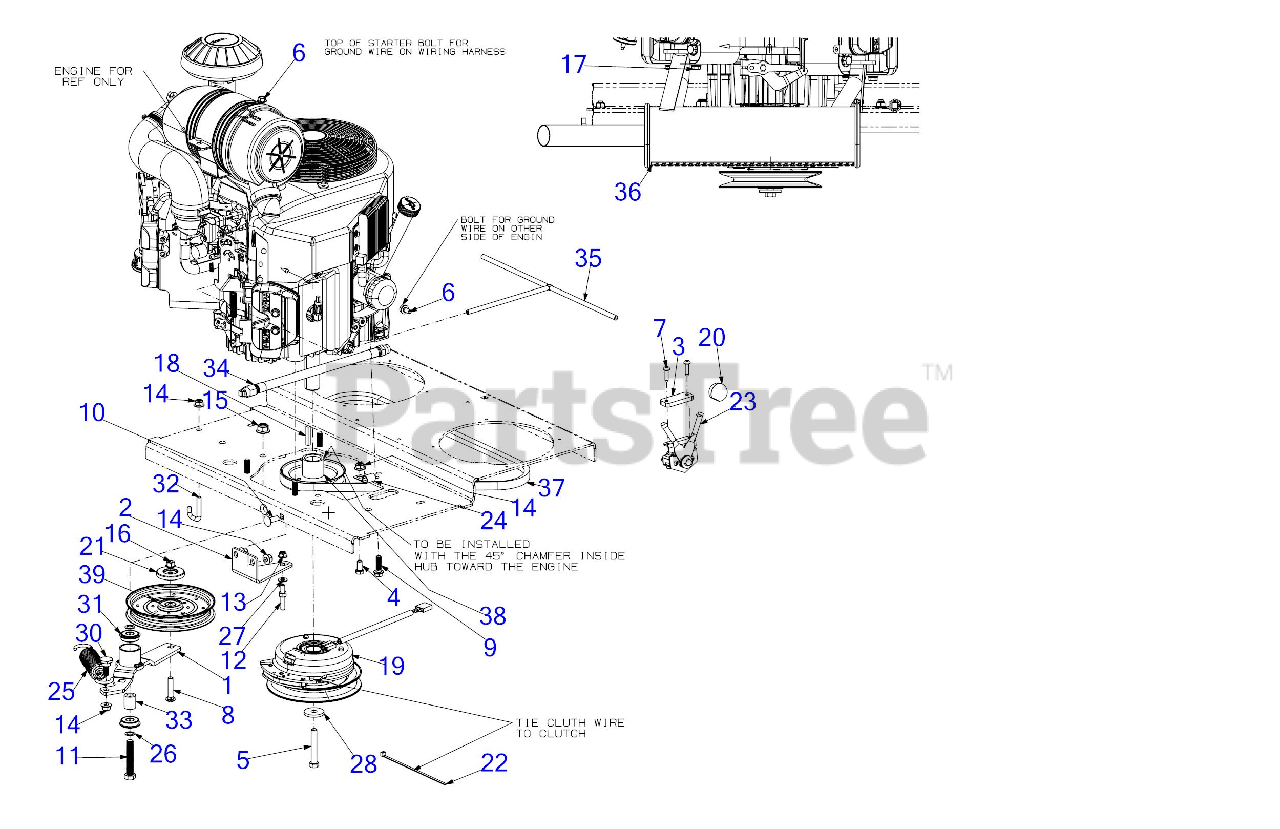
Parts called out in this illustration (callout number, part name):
1	IDLER ARM EXTENSION KIT
4	HEX SCREW 3/8-16 x .75
5	SCREW 7/16-20:2.75 GR5
6	SCREW M8 x 1.25 x 16MM GR8.8
7	SCREW 1/4-20 x 1.0
8	CARRIAGE BOLT 3/8-16 x 1.75 GR5
9	SCREW 3/8-16 x 1.25 GR5
10	CARRIAGE BOLT 3/8-16 x 1.00 GR5
11	SCREW 1/2-13 x 2.75 GR5
13	FLANGE LOCK NUT 5/16-18
16	HEX LOCK NUT
17	HEX FLANGE NUT
18	SQUARE KEY 1/4 x 1.50
19	ELECTRIC PTO CLUTCH
19	CLUTCH HARNESS 11.625
21	PULLEY CAP
22	7" CABLE TIE
23	THROTTLE CONTROL
24	J TYPE CLIP
25	EXTENSION SPRING W/HOOK
26	WASHER .510 x .750 x .033
27	FLAT WASHER
28	FLAT WASHER .45 x 1.5 x .172 HT
30	SHOULDER SCREW .625 x .302 x 3/8-16
31	ROLLER BEARING .5X1.37X.44
32	ROD SPRING HOOK
33	SPACER 0.51 X 0.88 X 1.00
34	OIL DRAIN HOSE
35	ROLLOVER VENT HOSE ASSEMBLY
36	KAWASAKI MUFFLER
37	TRANSMISSION BELT 61.5
38	PULLEY - PUMP DRIVE
39	IDLER PULLEY
